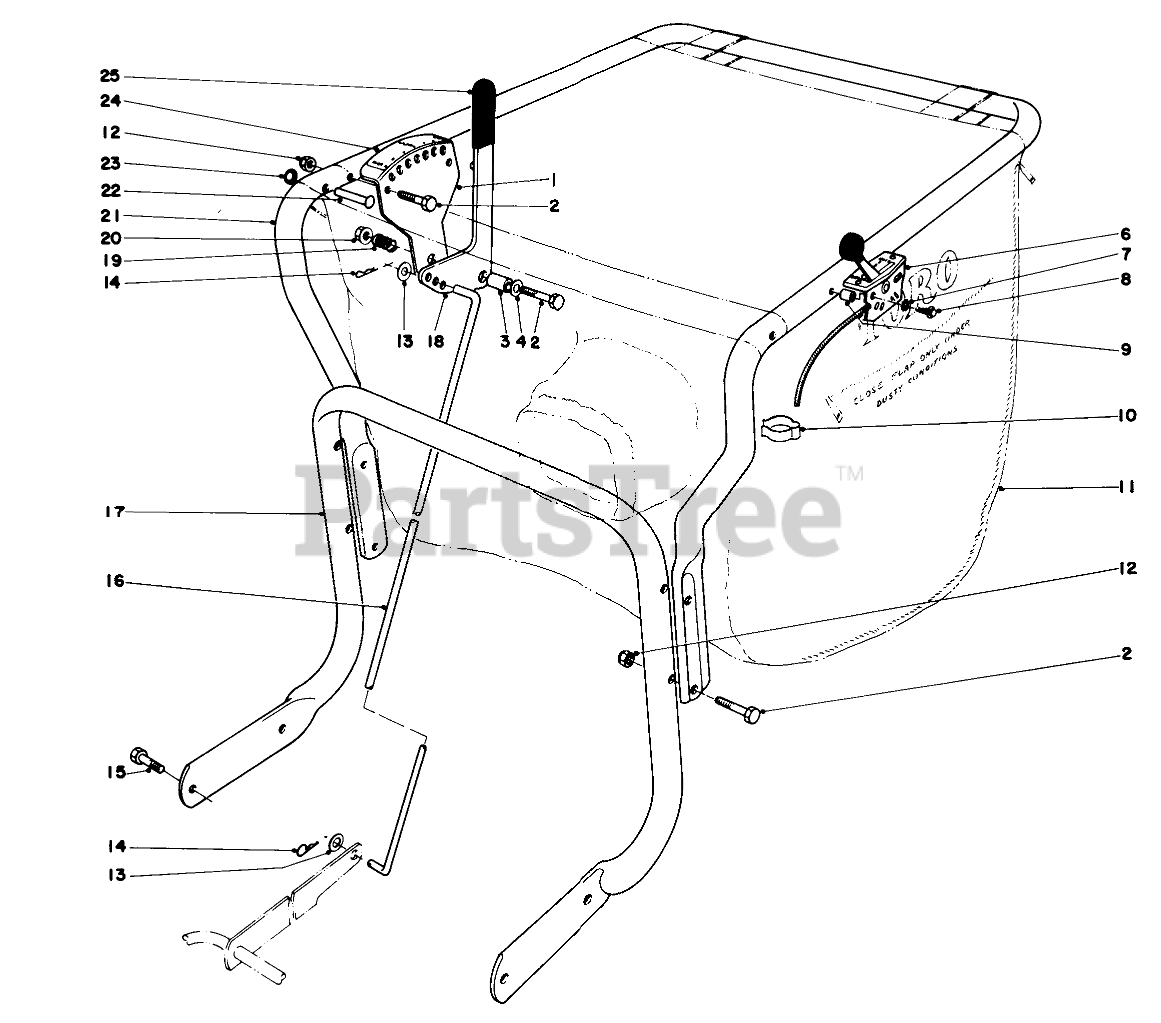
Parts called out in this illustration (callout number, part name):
1	Adjustment Bracket
2	SCREW-HH
3	SPACER
4	WASHER-FLAT
6	THROTTLE CONTROL
7	WASHER-LOCK, EXT
8	10-24 X 1 PAN HD SCR
9	SPACER
10	BODEN CLIP
11	Bag-Vacuum
12	NUT-LOCK, CONE
13	WASHER-FLAT
14	PIN-COTTER
15	SCREW-HH
16	HEIGHT ADJ. ROD
17	HANDLE
18	Handle-Adjustment
19	SPRING-COMPRESSION
20	NUT-HF
21	HANDLE-UPPER, VACUUM
22	RIVET
23	NUT-PUSH IN
24	HT ADJ DECAL
25	GRIP-HANDLE
